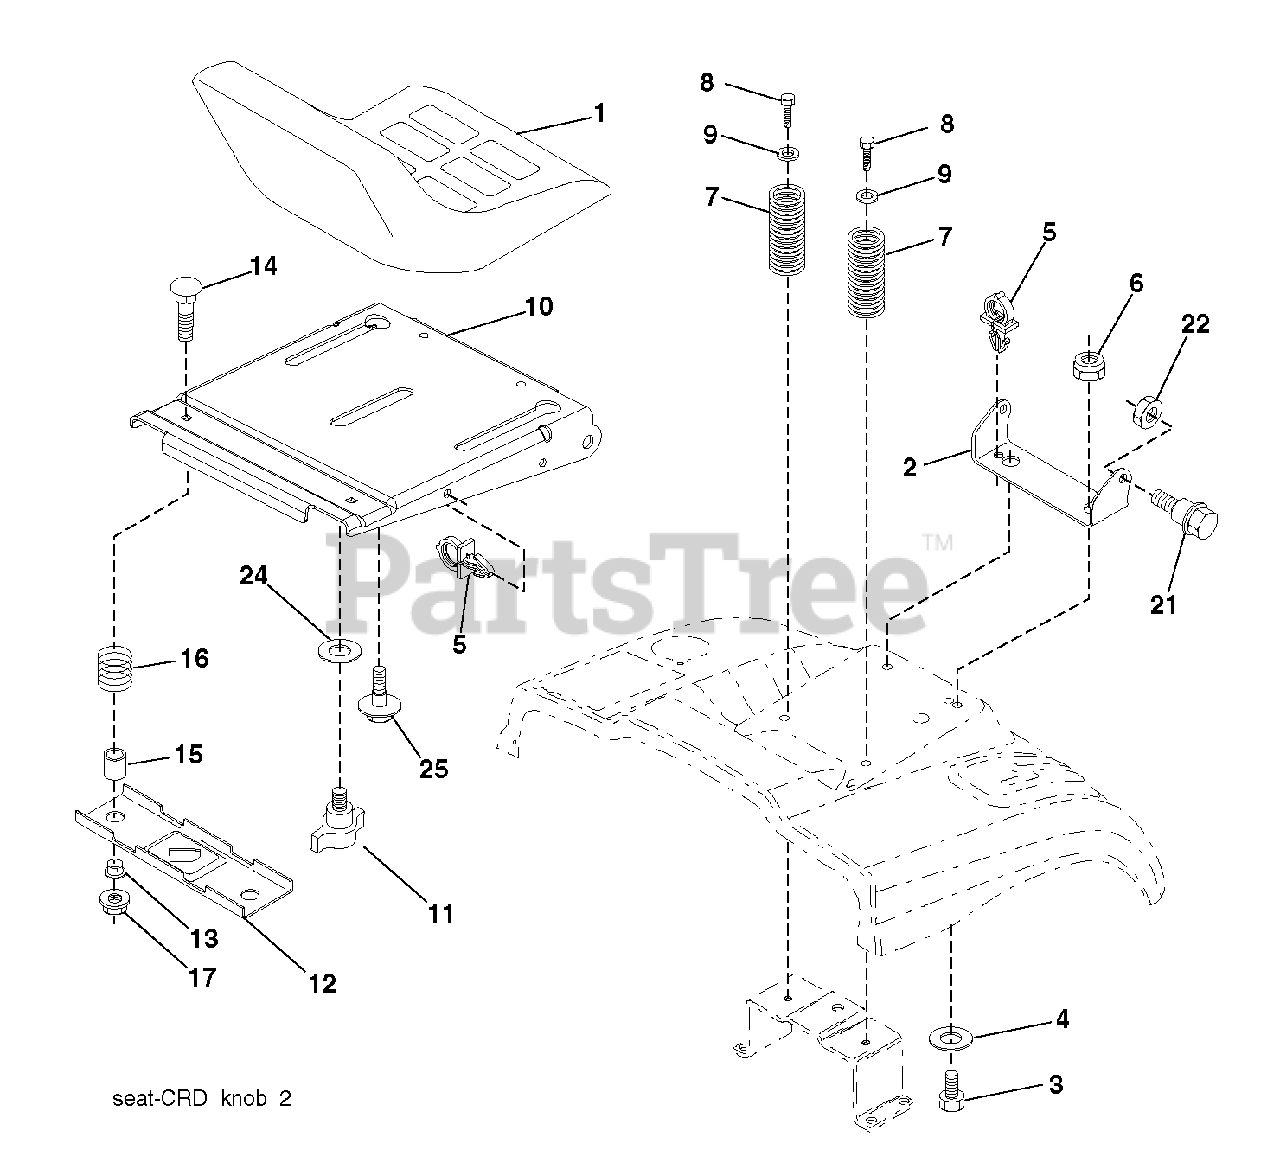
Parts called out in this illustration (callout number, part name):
1	SEAT.XG090.BLK.KB/BLT.NO-LOG
2	SEAT PIVOT BRKT
3	BOLT, HEX 3/8-16X1
6	NUT
7	SPRING COMPRESSION
8	SCREW 3/8-16X1
9	WASHER
10	PAN.ASM.SEAT.1SLOT
11	KNOB.SEAT.ADJ.WINGNUT
12	BRKT.MNTNG.SWITCH.SEAT
14	BOLT.ROUND.HEAD.SQUARE.NECK
15	SPACER SPLIT 28X.96
17	NUT T
21	BOLT.SHOULDER.5/16-18
22	NUT.71038.31-18.HEX.NYLOCK
